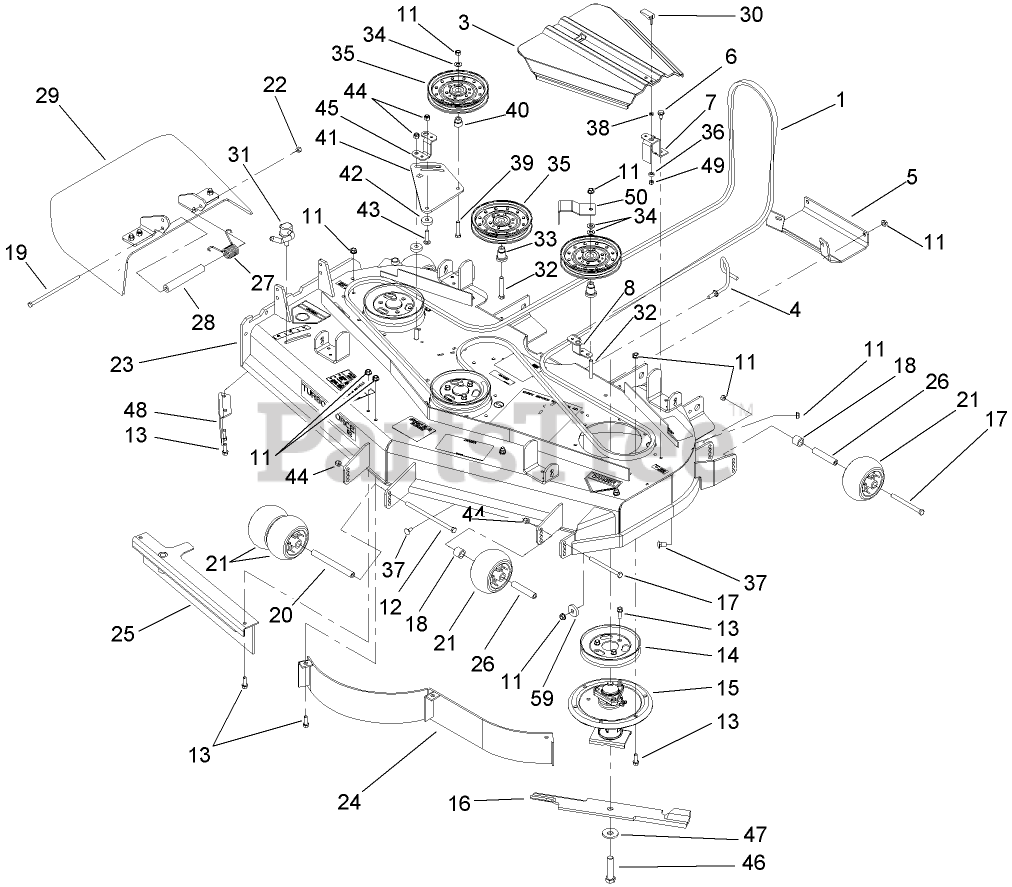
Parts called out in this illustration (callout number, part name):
3	COVER-BELT
4	GUIDE-BELT
5	Plate-Skid
6	SCREW-HWHTF
7	BRACKET-COVER
8	BRACKET-COVER, TALL
11	NUT-HHF, WHIZ
12	SCREW-HH
13	SCREW-HWH
14	Pulley
15	SPINDLE ASM
16	BLADE-18IN, HI FLOW
17	SCREW-HH
18	TUBE-SPACER
19	SCREW-HH
20	SPACER-WHEEL
21	ROLLER-SCALP, ANTI
22	NUT-LOCK, NI
23	DECK ASM
26	TUBE-SPANNER
27	SPRING-TORSION
28	SPACER
29	RUBBER DEFLECTOR ASM
30	HANDLE-LATCH, SWELL
31	LEVER ASM
32	SCREW-HH
33	MOUNT-PULLEY
34	WASHER-FLAT
35	Idler-Flat
36	BUSHING-LATCH, SWELL
37	SCREW-CARR
38	WASHER
39	SCREW-HH
40	BUSHING-IDLER
41	Plate-Idler
42	Spacer
43	SCREW-CARR
44	NUT-LOCK, NI
45	BRACKET-COVER, SHORT
46	Screw-Cap
47	Washer-Blade Bolt, Heavy
48	BAFFLE-DISCHARGE
49	NUT-LOCK, HH
50	GUIDE-BELT
59	WASHER
